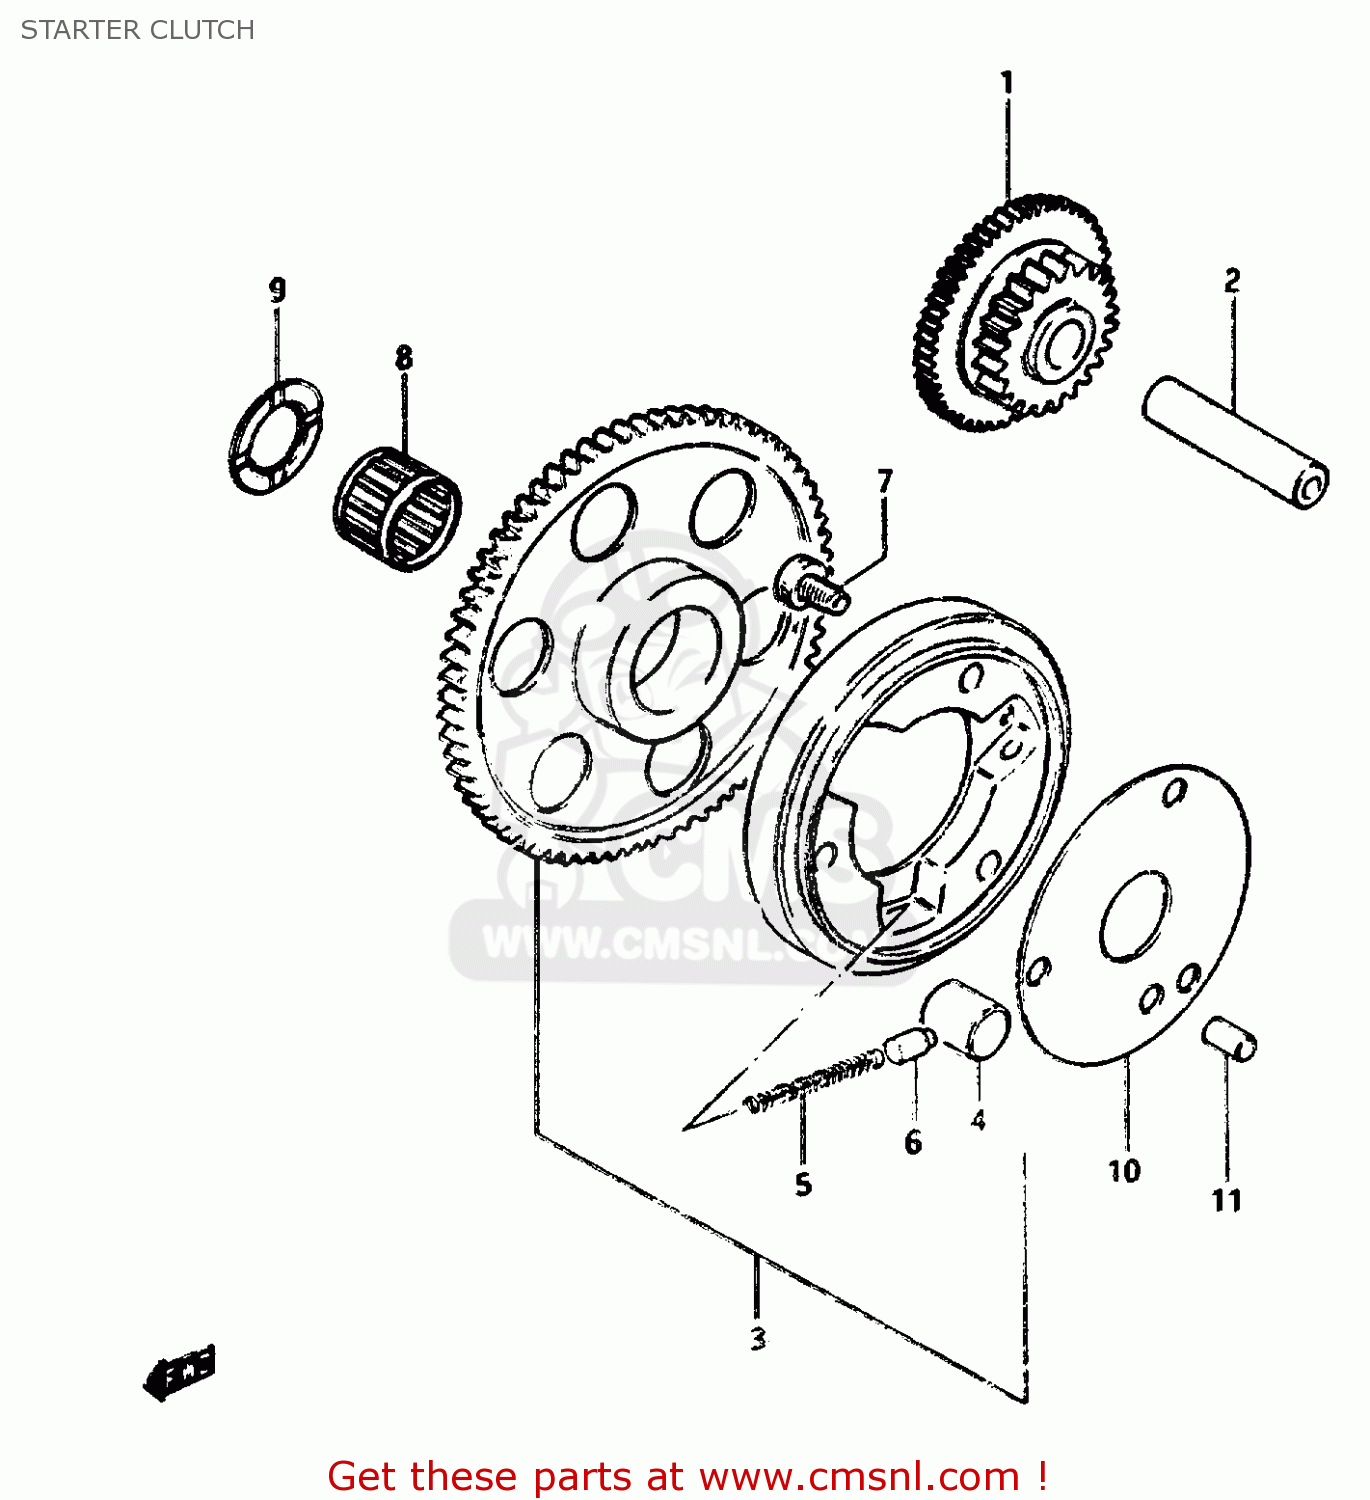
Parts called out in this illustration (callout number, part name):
1	GEAR,STARTER IDLE
2	PIN(7.4X13X56)
3	CLUTCH SET,STARTER
4	ROLLER(15X13)
5	SPRING
6	PIECE,PUSH
7	BOLT
8	BEARING(29X35X24)
9	WASHER(29X41X2.5)
10	SHIM,STARTER CLUTCH HUB
11	PIN
